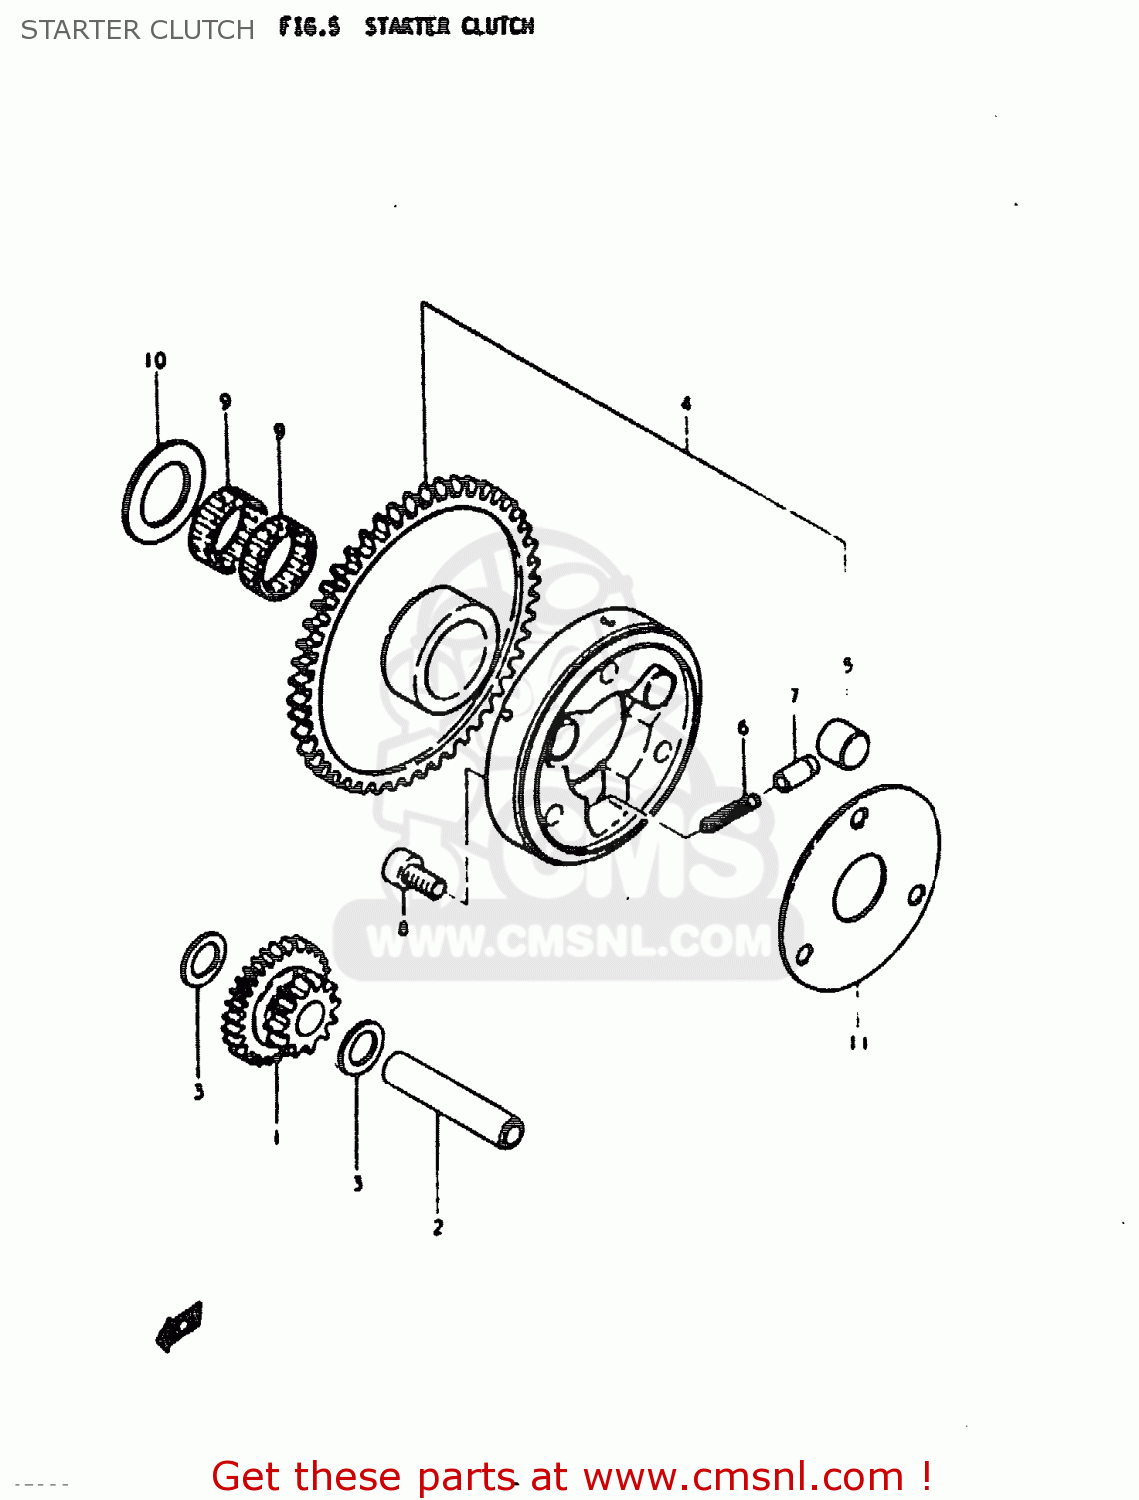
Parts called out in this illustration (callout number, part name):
1	GEAR, STARTER IDLE
2	PIN(7.4X13X56)
3	WASHER
4	STARTER CLUTCH SET
5	ROLLER(15X13)
6	SPRING
7	PIECE,PUSH
8	BOLT
9	BEARING(25X29X9.9)
10	WASHER
11	SHIM,STARTER CLUTCH HUB
